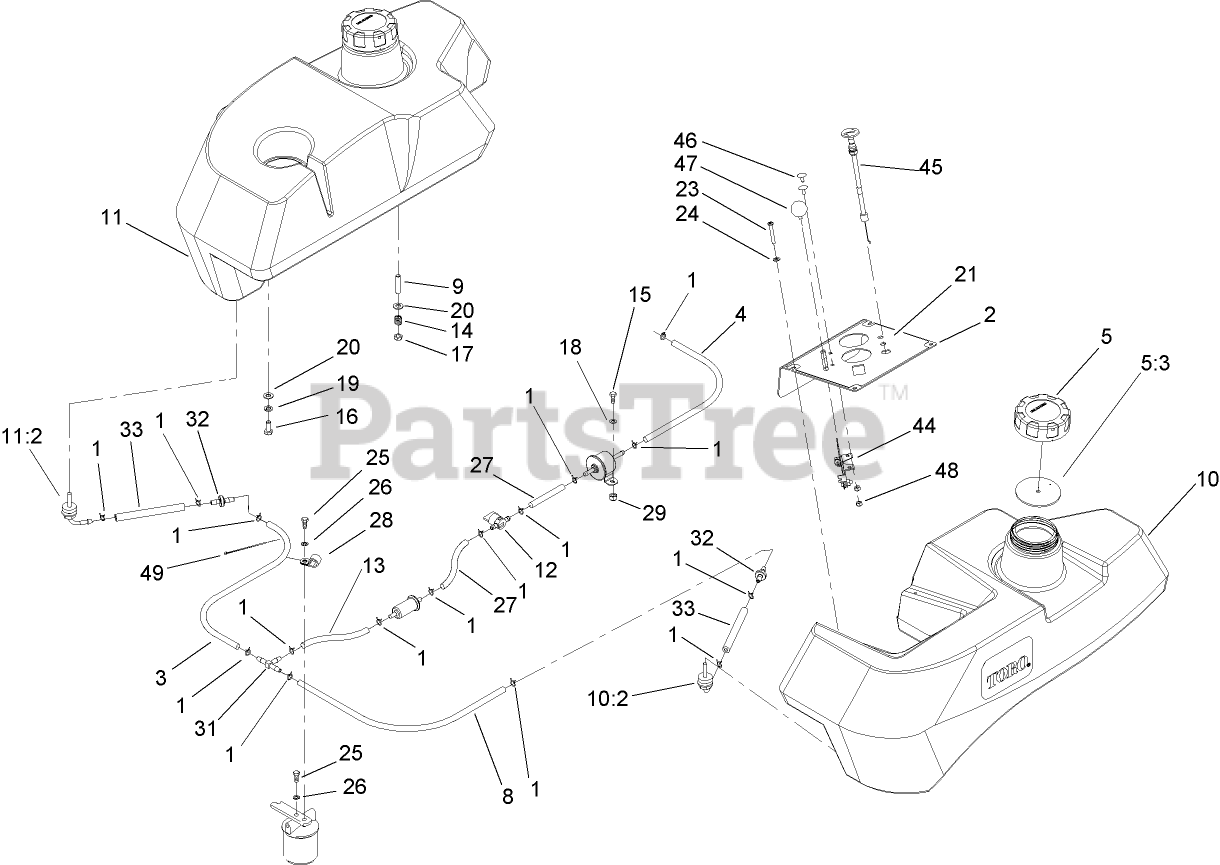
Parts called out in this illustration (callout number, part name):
2	PANEL-CONTROL
3	HOSE-FUEL
4	Hose-Fuel
5	GAS CAP ASM
5:3	GASKET-CAP, GAS
8	HOSE-FUEL
10	LH Fuel Tank ASM
10:2	FITTING-FUEL, BULKHEAD
11	RH Fuel Tank ASM
11:2	FITTING-FUEL, BULKHEAD
12	VALVE-FUEL
13	HOSE-FUEL
14	SPRING-TANK, FUEL
15	SCREW-HH
16	SCREW-HH
17	NUT-LOCK, NI
18	WASHER-FLAT
19	WASHER-LOCK
20	WASHER-PLAIN
21	Decal-Panel, Control
24	WASHER-SPRING
25	SCREW-HH
26	WASHER-LOCK
27	HOSE-FUEL
28	CLIP-LOOM
29	NUT-HF
31	FITTING-TEE, BARBED
32	VALVE-CHECK, FUEL
33	HOSE-FUEL
44	CABLE-THROTTLE
45	Control-Choke, Push / Pull
46	BOLT-CARR
47	KNOB-BALL
48	NUT-LOCK, NI
49	TIE-PLASTIC
